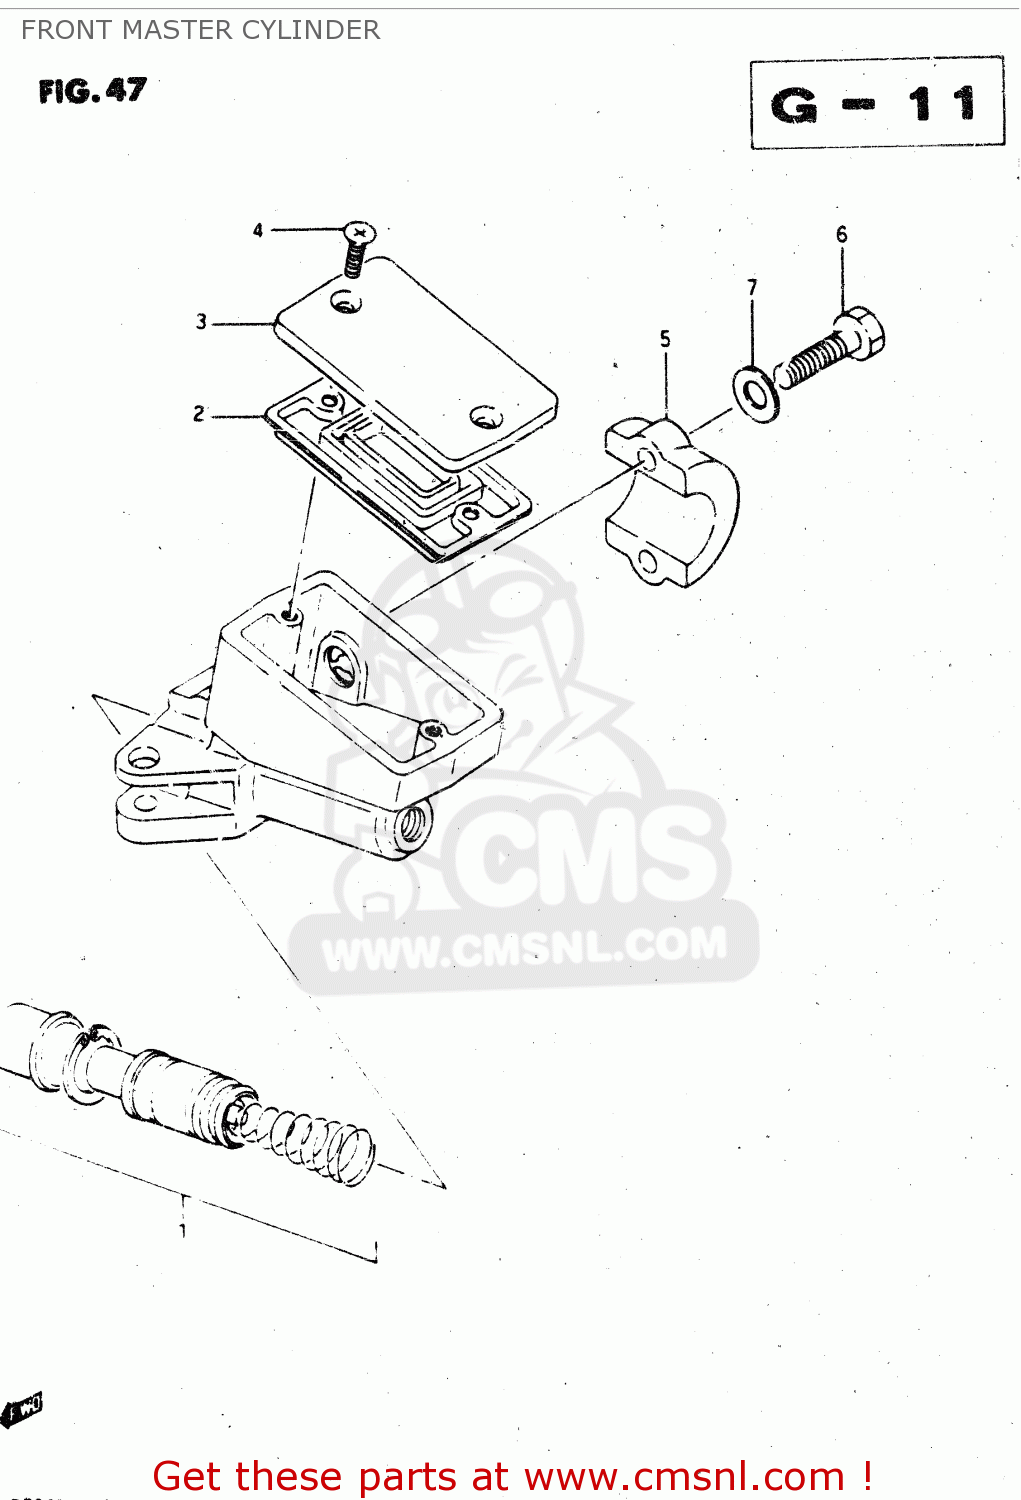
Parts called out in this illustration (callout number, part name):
1	PISTON & CUP SET
2	3
3	CAP
4	SCREW
5	HOLDER,MASTER CYLINDER
6	BOLT
7	WASHER
